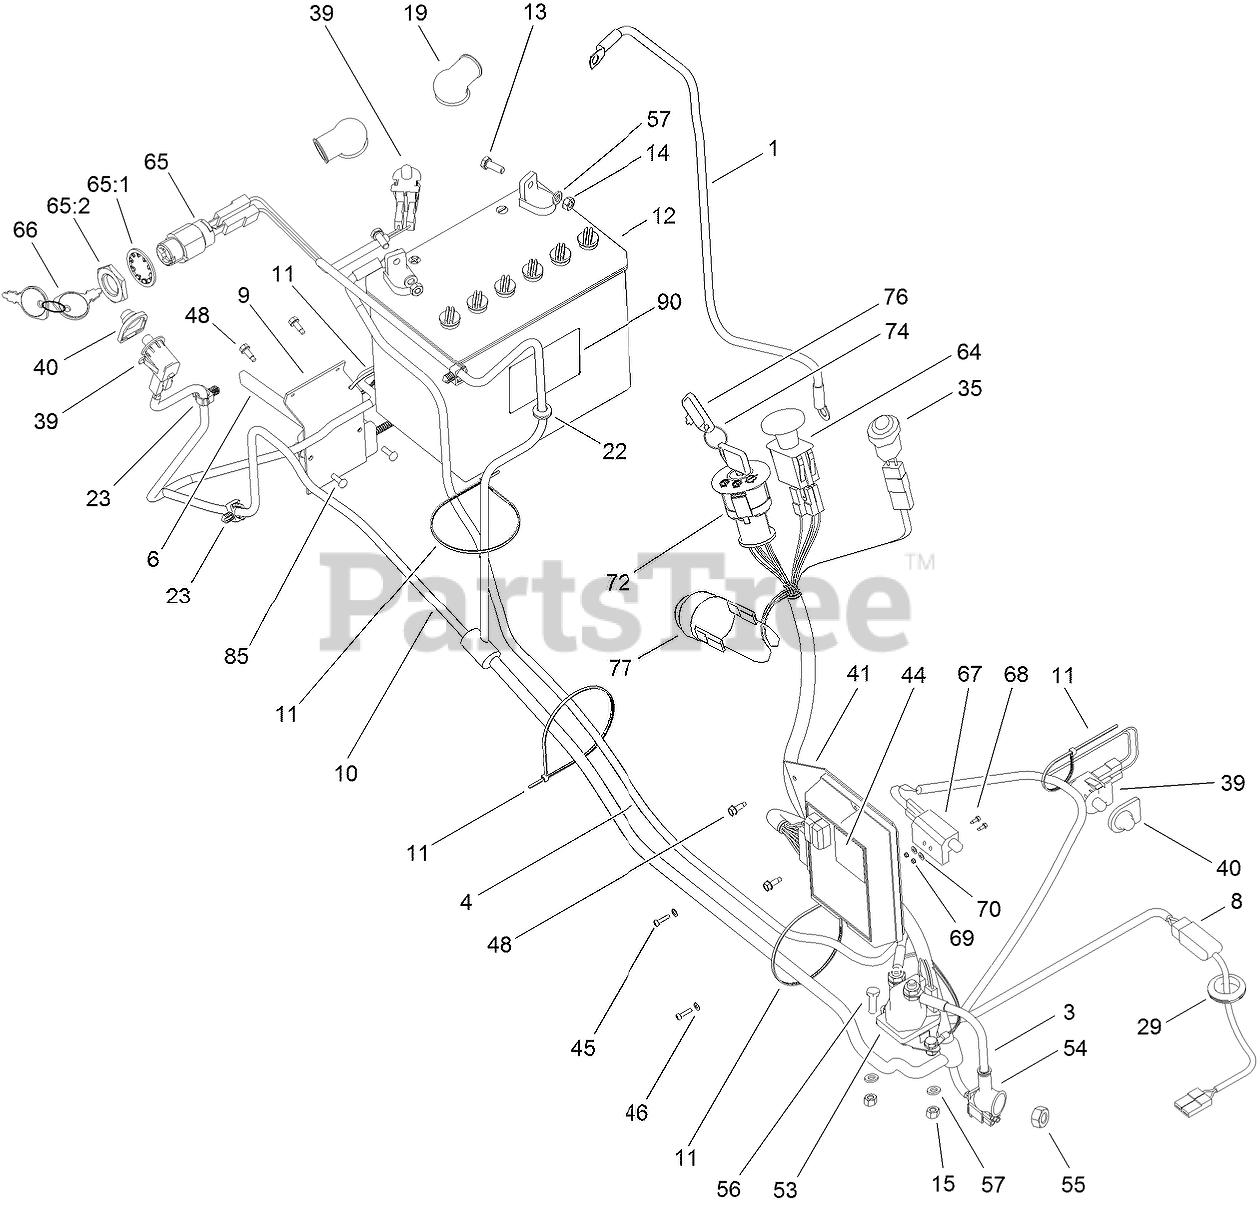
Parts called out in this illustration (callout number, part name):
1	CABLE-BATTERY, NEGATIVE
3	LEAD-STARTER, ELECTRIC
4	CABLE-BATTERY, POSITIVE
6	SWITCH-OMRON
8	HARNESS-CLUTCH
9	BRACKET-SWITCH
10	HARNESS-WIRING
11	TIE-CABLE
12	BATTERY
13	SCREW-HH
14	NUT-HEX
15	NUT-LOCK
19	BOOT-RUBBER
22	BUSHING
23	CLIP-SNAP
29	BUSHING
35	LAMP-INDICATOR
39	SWITCH-DELTA
40	COVER-PROTECTIVE
41	BRACKET-SUPPORT, MODULE
44	MODULE-CONTROL
46	WASHER
48	SCREW-TAP
53	Solenoid
54	BOOT-RUBBER
55	NUT-HHF
56	SCREW-HH
57	WASHER
64	SWITCH-PTO
65	STARTER SWITCH ASM
65:1	WASHER-TOOTH, INTERNAL
65:2	NUT-HH
66	KEY-IGNITION
67	SWITCH-DELTA
69	NUT-HEX
70	WASHER
72	SWITCH-IGNITION
76	KEY-IGNITION
77	BUZZER
85	Screw
90	DECAL-DANGER
